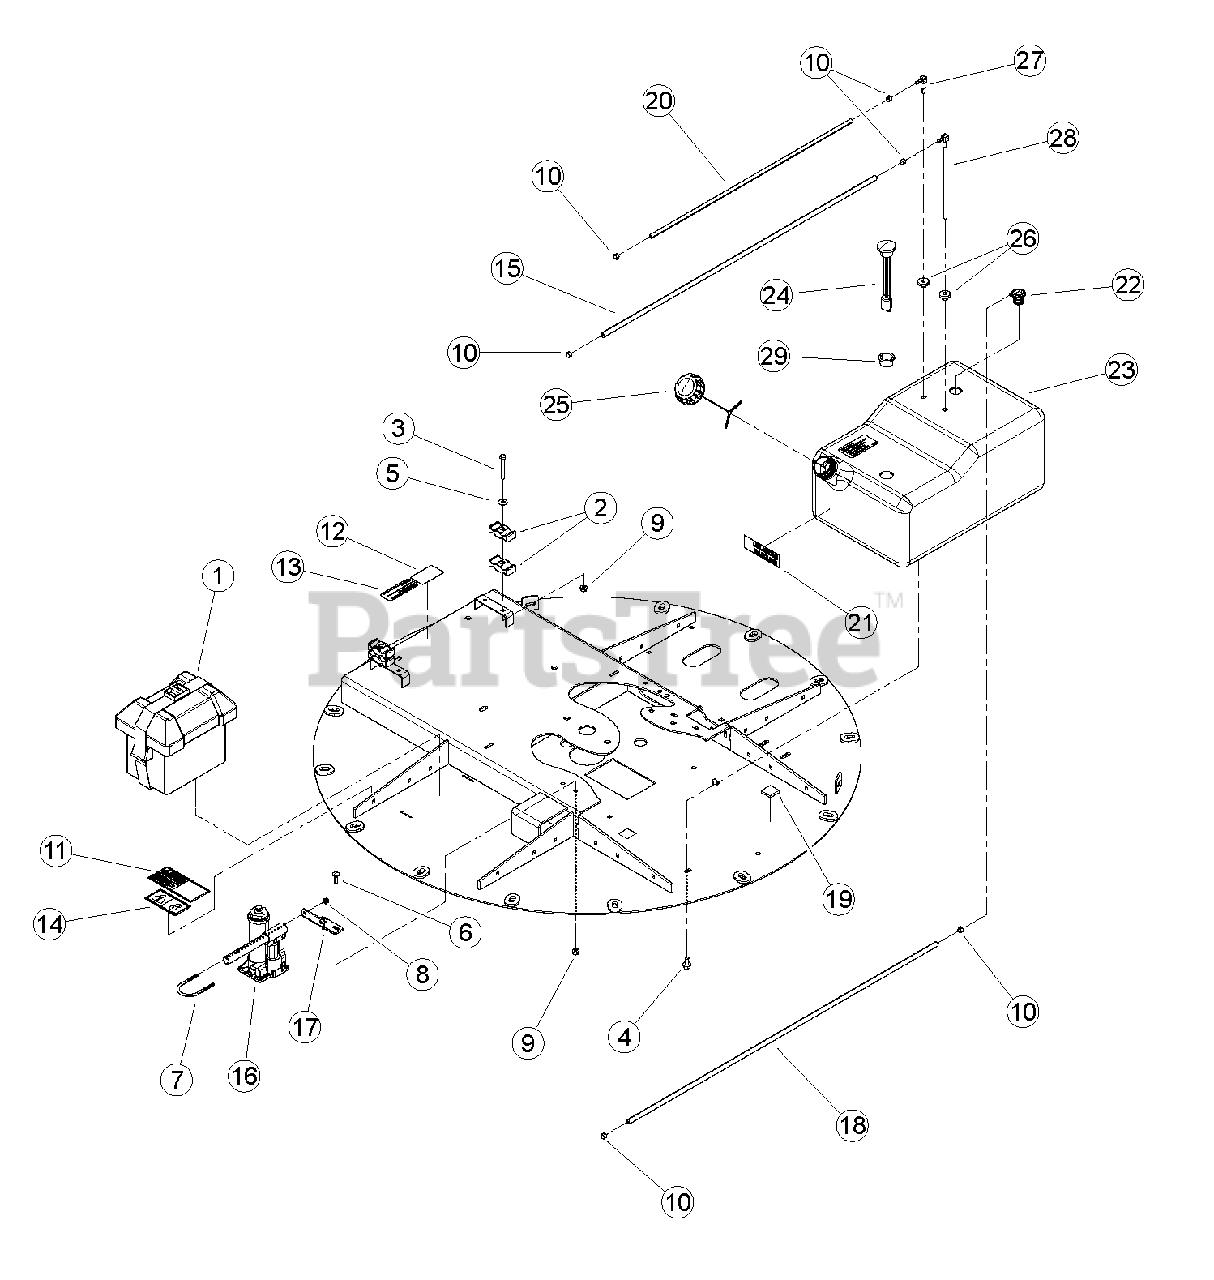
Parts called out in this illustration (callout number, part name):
1	BOX, SMALL BATTERY
2	CLAMP, PLASTIC HOSE
3	BOLT, 5/16 X 2-1/2 G5 HX CAP ZP
4	BOLT, 3/8 X 3/4 FLANGE NC
5	WASHER, 5/16" FLAT ZP
6	BOLT, 5/16 X 1" GR5 CRG ZP
7	U-BOLT, 1/4 X 1-1/2 PIPE
8	NUT, 1/4-20 NYLOCK-FLANGE
9	NUT, 5/16-18 NYLOCK-FLANGE
10	CLAMP, 15/32 SPRING
11	DECAL, HITCH TRANSPORT
12	DECAL, P215/70R15 LOAD RATING
13	DECAL, EPA EVAP
14	DECAL, LOCK
15	HOSE, 38" FUEL LINE
16	JACK, HYDRAULIC 2 TON
17	PLATE, JACK MOUNT
18	HOSE, 43 INCH FUEL LINE
19	PAD, FOAM FUEL TANK DAMPER
20	HOSE, 28 INCH FUEL LINE 1/4"
21	DECAL, UNLEADED GASOLINE
22	VALVE, ROLL OVER
23	TANK, ROTOMOLDED FUEL
24	GAUGE, FUEL LEVEL KELCH 100
25	CAP, NON-VENTED EPA/CARB APPROVED
26	GROMMET, TANK FITTING
27	FITTING, TANK VENT
28	FITTING, TANK FUEL PICK-UP TUBE
29	GROMMET, KELCH 100 GAUGE
